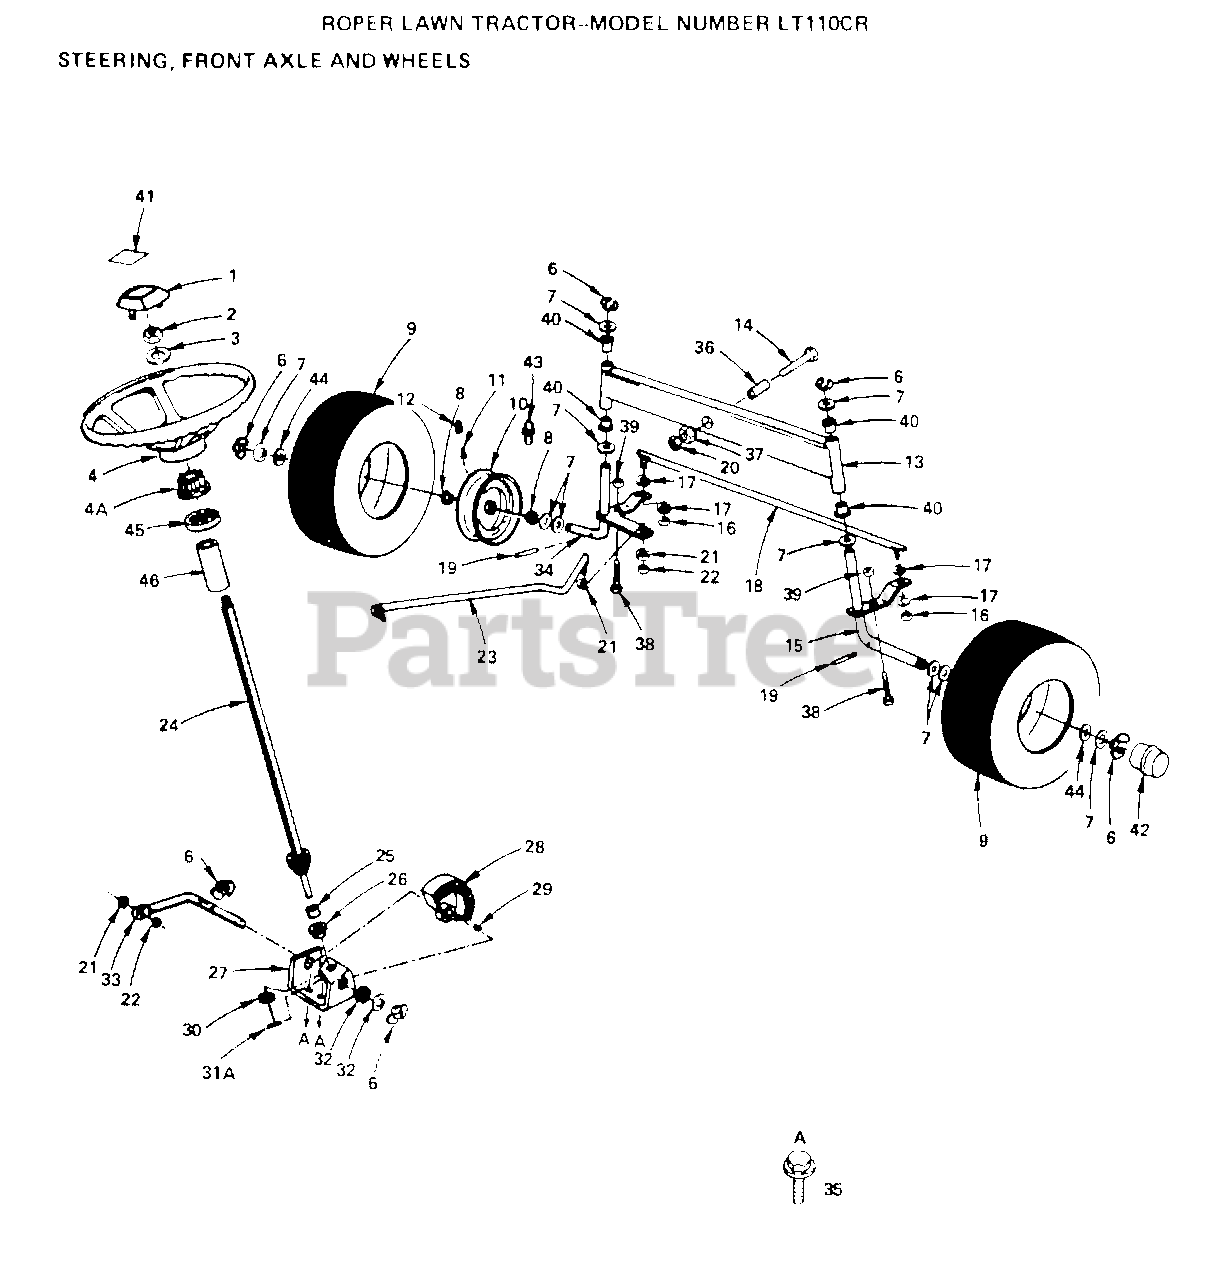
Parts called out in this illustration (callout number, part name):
1	INSERT-WHEEL LT
2	NUT
3	WASHER
4A	ADAPTER LT
6	RING
8	"FLANGE, BEARING"
11	VALVE STEM LT
12	VALVE CAP
13	AXLE ASSY YTV
16	NUT
17	LOCKWASHER
20	LOCKNUT M
21	LOCKWASHER
23	DRAG LINK LTV
24	SHAFT ASSY LT
25	SHAFT SPACER LT
26	BUSHING
28	GEAR-SECTOR T
30	WASHER D
32	WASHER .T
33	ROD STEERING LT
34	SPINDLE LH LTV
35	SCREW
38	BOLT
39	NUT
40	COL. SRTG. BEAR.
41	DECAL - STEERING WHEEL
42	HUB CAP
43	FITTING LT
44	WASHER LT
